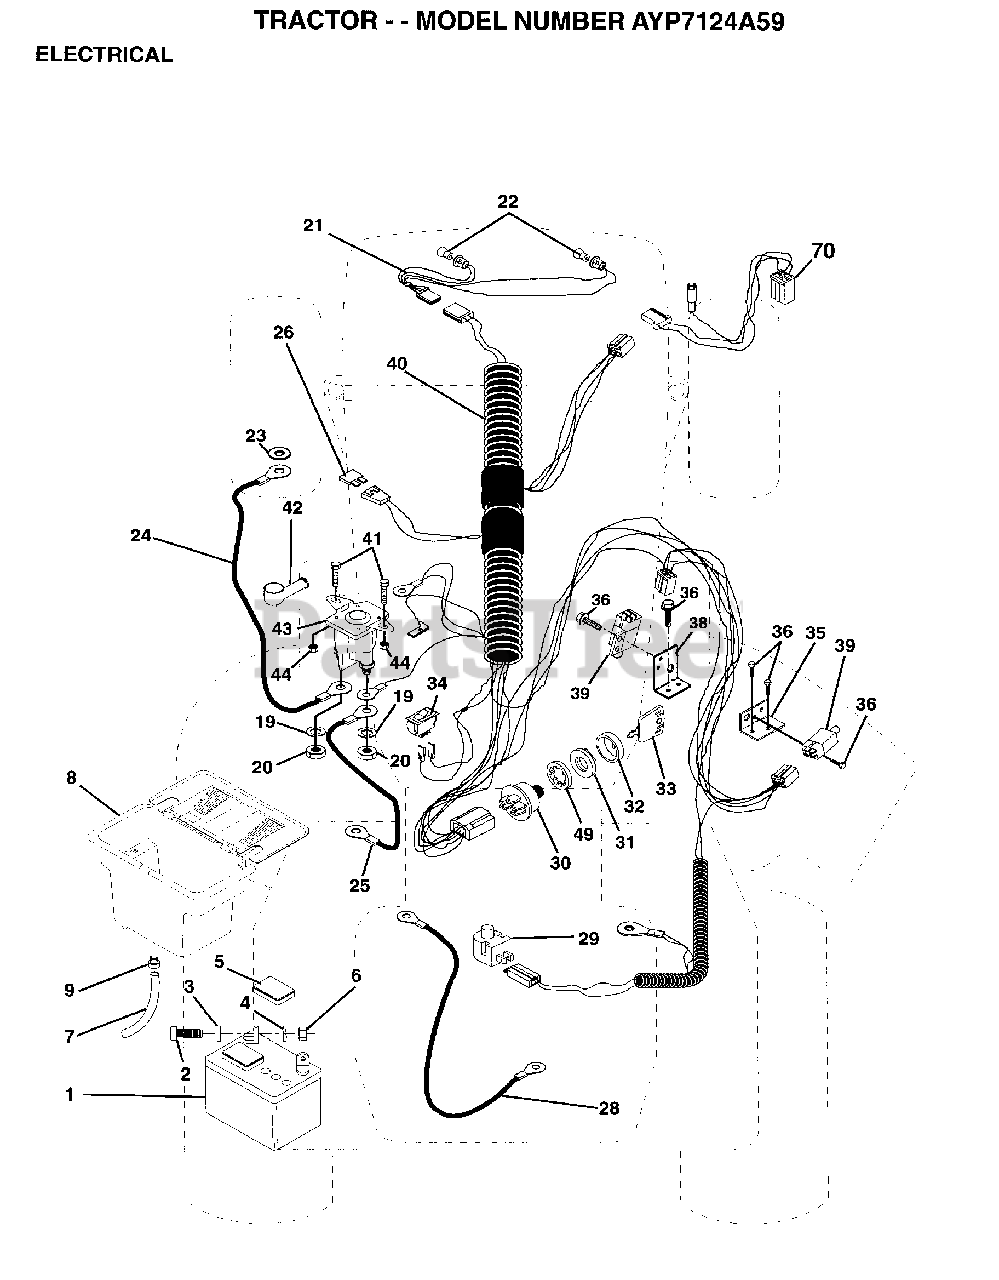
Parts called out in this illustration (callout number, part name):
2	BOLT LT
3	WASHER
4	LOCKWASHER
5	"CAP,BATTERY "
7	TUBE T
9	HOSE CLAMP T
20	NUT
21	"HARNESS,LIGHT SOC"
22	HEADLAMP BULB
23	LOCKWASHER
24	"CABLE T, BATTERY"
26	FUSE HYT
28	CABLE T
29	SWITCH SEAT
32	COVER KEY SWITCH
33	KEY STEEL DELTA
34	SWITCH LT
35	BRACKET LT
36	SCREW
38	BRACKET SWITCH IN
39	SWITCH INTERLOCKT
40	HARNESS IGN DASH
41	BOLT HXHD FIN
44	NUT HXKEP 1/4X20
49	LOCKWASHER
70	HARNESS ENG DUAL
